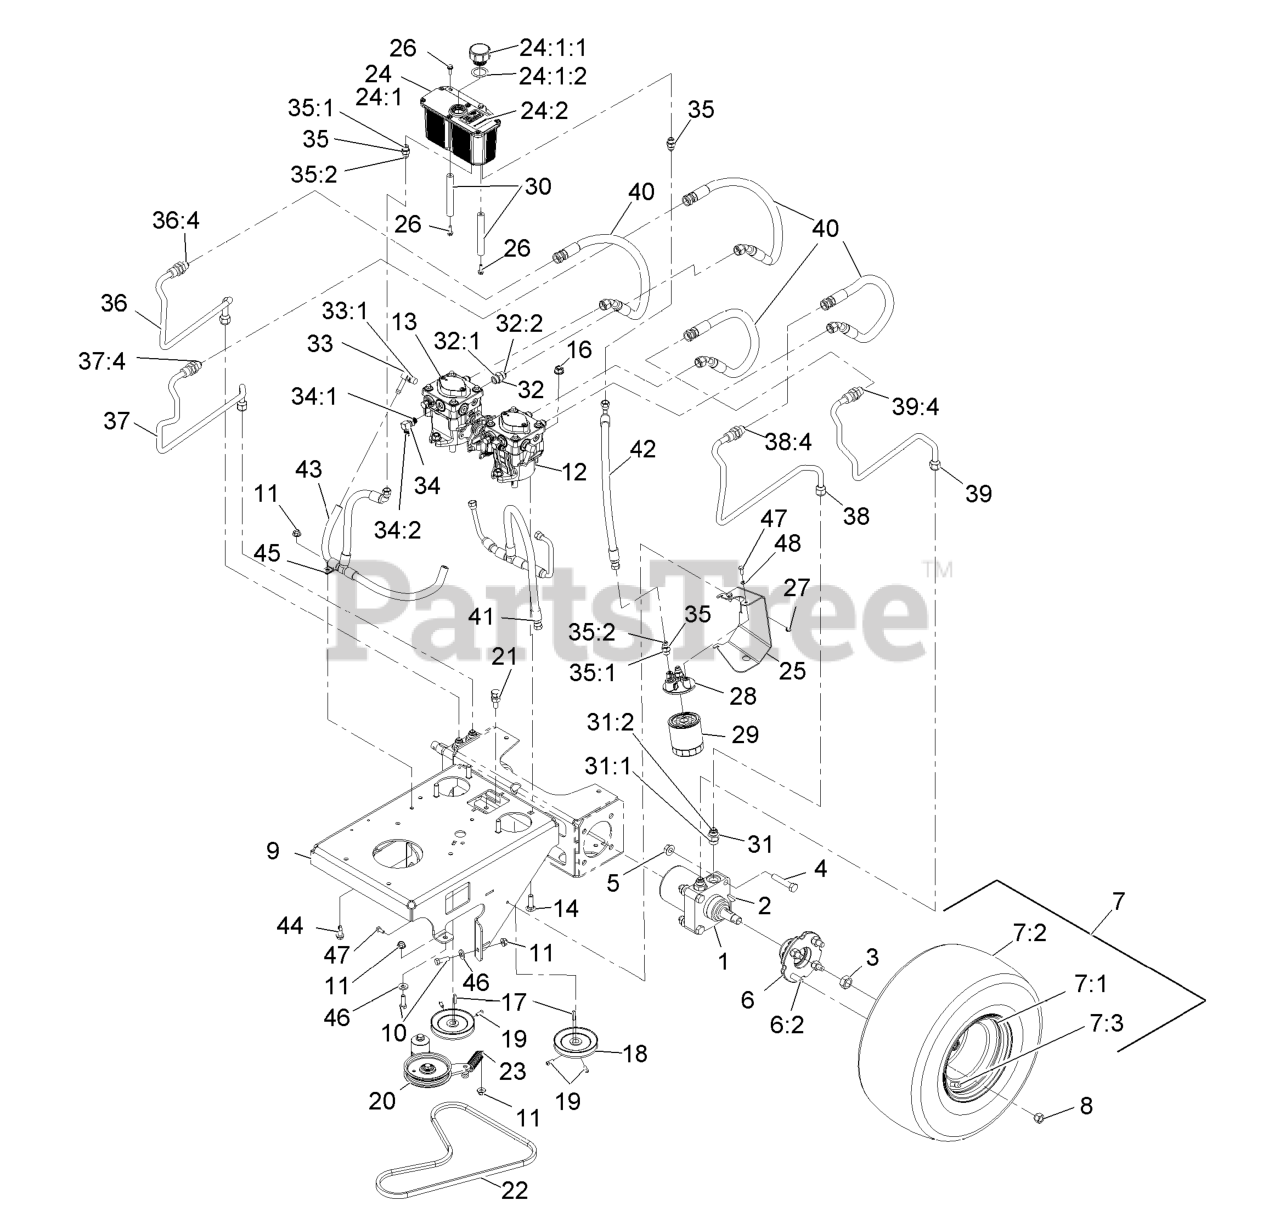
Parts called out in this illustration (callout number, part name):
1	HYD MOTOR ASM
2	KEY-WOODRUFF
3	NUT-MOTOR, WHEEL
4	SCREW-HH
6	WHEEL HUB ASM
6:2	STUD-TYPE, DRIVE
7	WHEEL/TIRE ASM
7:1	RIM-8 INCH
7:3	Stem-Valve
8	NUT-LUG
9	ENGINE BASE
10	SCREW-HH
11	NUT-HF, NI
12	PUMP - HYDRAULIC
13	PUMP-HYDRAULIC
14	SCREW-HH
16	NUT-HF, NI
18	PULLEY-PUMP
19	SCREW-SET
20	Pump Idler Asm
22	BELT-V
23	SPRING-EXTENSION
24	RESERVOIR ASM
24:1	Reservoir-Hyd
24:1:1	Cap-Reservoir, HYD
24:1:2	GASKET-CAP
24:2	DECAL-HYDRAULIC TANK
25	PLATE-FILTER MOUNT
26	SCREW-HHF
28	HEAD-FILTER
29	FILTER-25 MICRON, BI-DIRE
30	ROD-RESERVOIR STAND
31	FITTING-STRAIGHT
31:1	O-RING
32	FITTING-STRAIGHT
33	FITTING-ELBOW, 90
33:1	O-RING
34	FITTING-90 DEG
35	FITTING-STRAIGHT
36	HYDRAULIC TUBE ASM
36:4	FACE SEAL O-RING #8
37	HYDRAULIC TUBE ASM
37:4	FACE SEAL O-RING #8
38	HYDRAULIC TUBE ASM LH
38:4	FACE SEAL O-RING #8
39	HYDRAULIC TUBE ASM LH
39:4	FACE SEAL O-RING #8
40	HOSE ASM-HYD HP 1/2
42	HOSE ASM-HYD LP 3/8X14.4
44	SCREW-TAPPING
45	CLIP-LOOM
46	WASHER-BELLEVILLE
47	SCREW-HH
48	WASHER-LOCK
